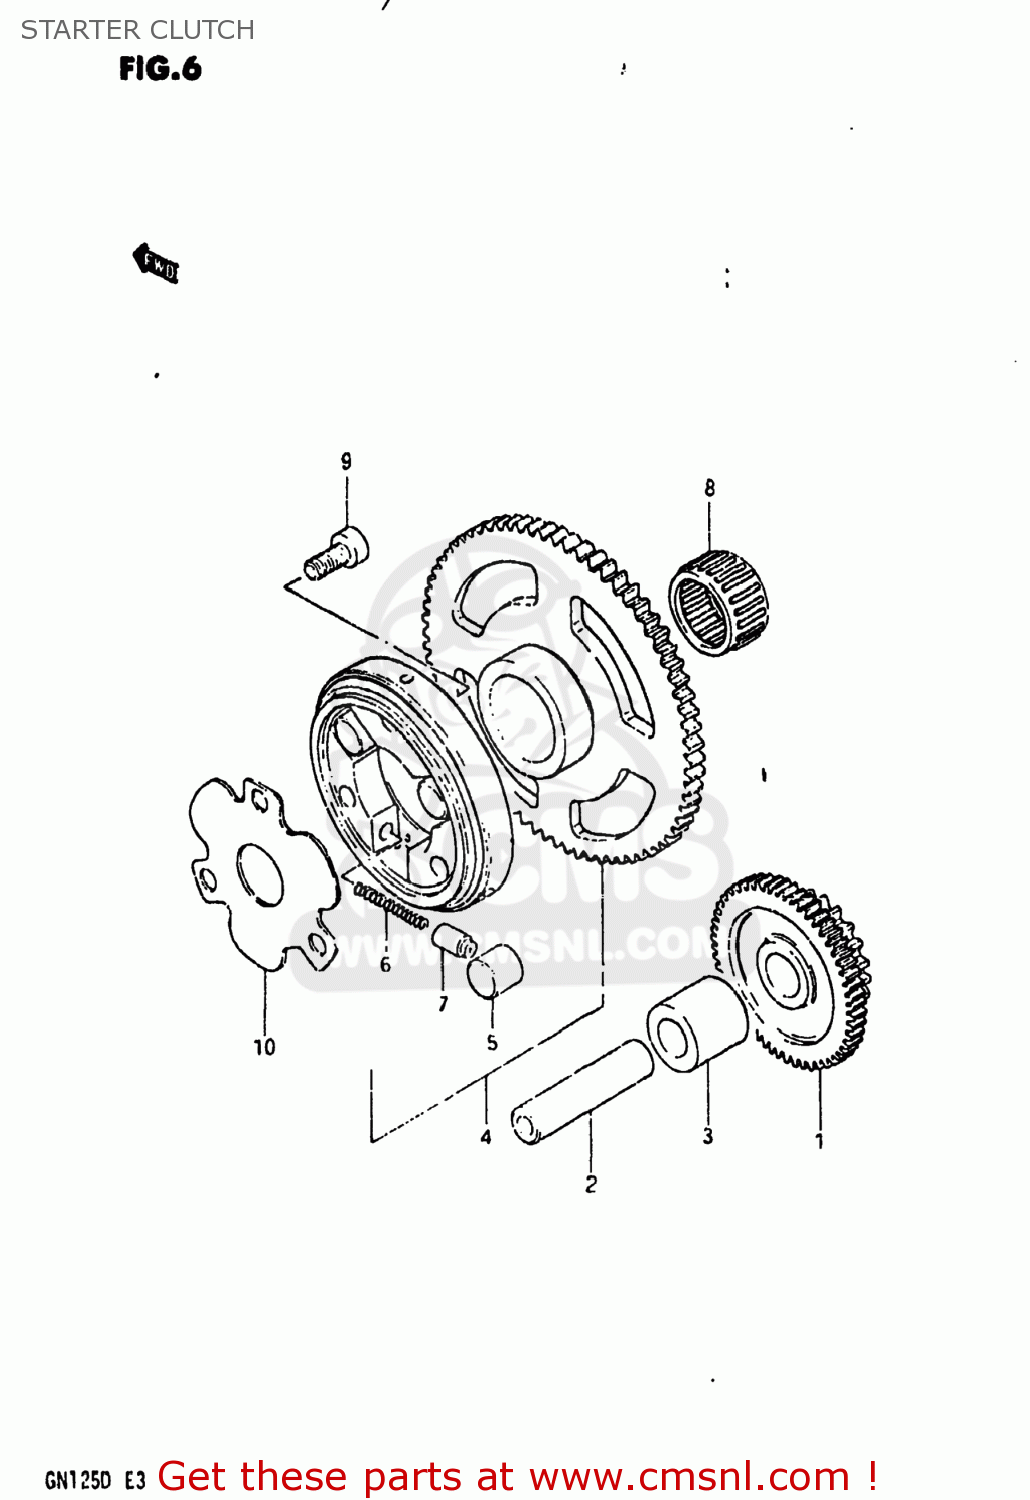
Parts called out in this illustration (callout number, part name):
1	GEAR,STARTER IDLER
2	PIN(7.4X13X56)
3	SPACER(13X19X19)
4	CLUTCH SET,STARTER
5	ROLLER(10X11)
6	SPRING
7	PIECE,STARTER CLUTCH PUSH
8	BEARING(22X28X16)
9	BOLT
10	SHIM,STARTER CLUTCH HUB
